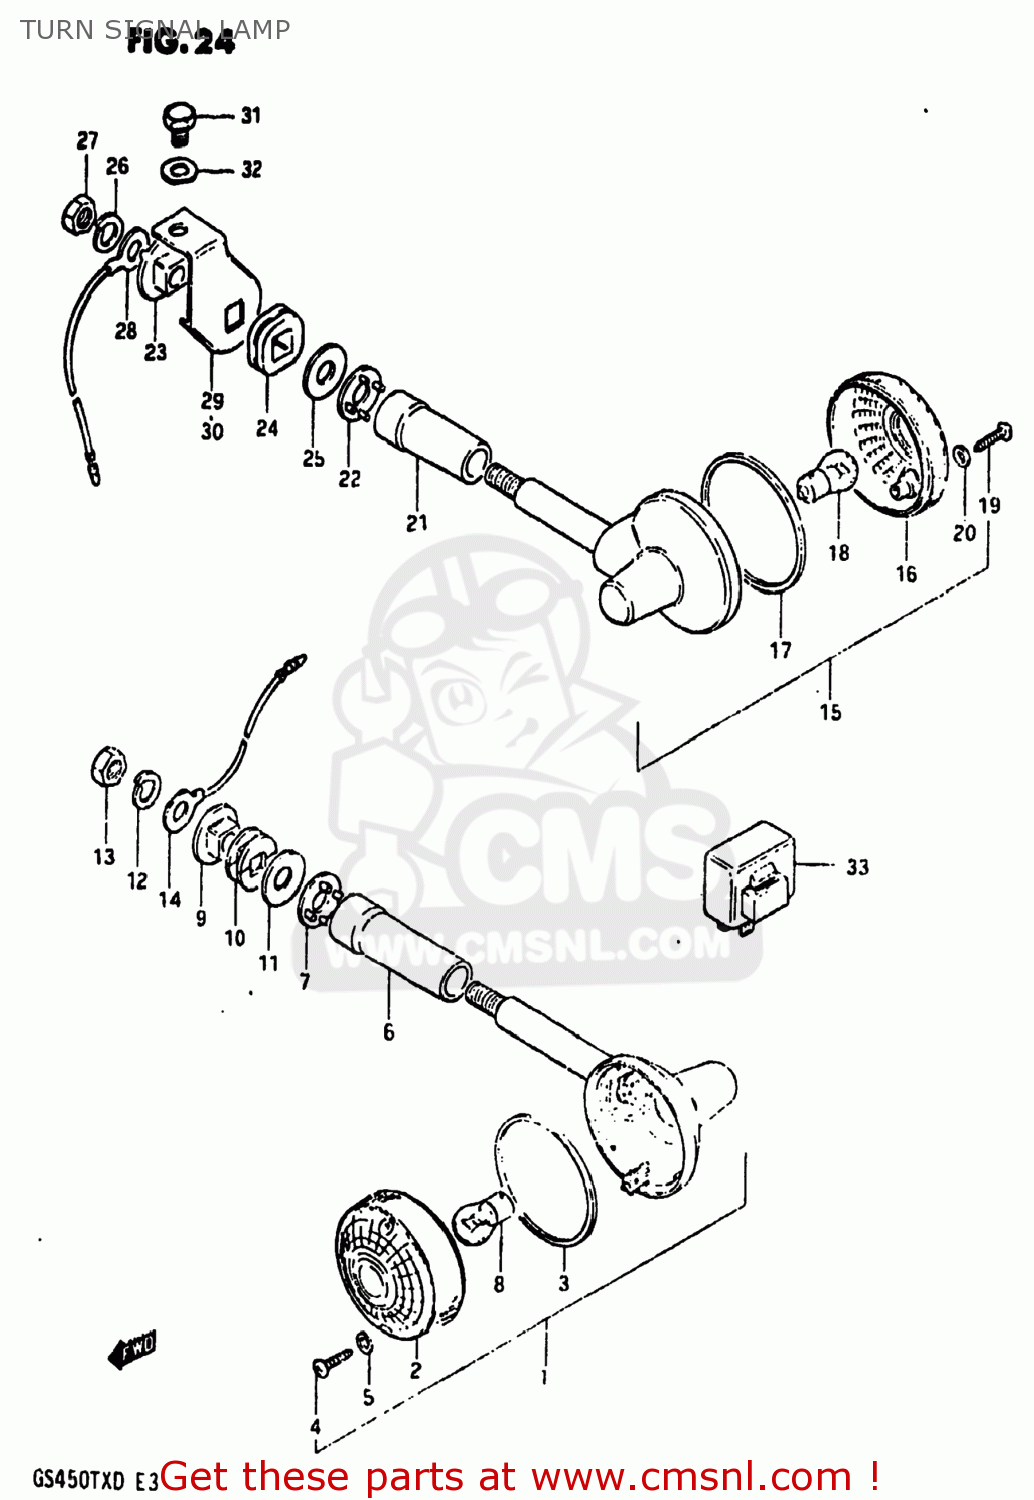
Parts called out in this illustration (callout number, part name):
1	LAMP ASSY,TURNSIGNAL
2	LENS
3	GASKET (NAS)
4	SCREW
5	GASKET (NAS)
6	COVER,STAY
7	SPACER
8	BULB(12V23W,STANLEY,A4577A)
9	SPACER
10	CUSHION
11	WASHER (10.5X30X2.3)
12	LOCK WASHER
13	NUT
14	LEAD WIRE,EARTH
15	LAMP ASSY,RR TURNSIGNAL
16	LENS
17	GASKET (NAS)
18	BULB(12V23W,STANLEY,A4577A)
19	SCREW
20	GASKET (NAS)
21	COVER
22	SPACER
23	SPACER
24	CUSHION
25	WASHER (10.5X30X2.3)
26	LOCK WASHER
27	NUT
28	LEAD WIRE,EARTH
29	BRACKET,RR TURNSIGNAL LAMP,R
30	BRACKET,REAR TURN SIGNAL
31	BOLT 8X12
32	WASHER
33	RELAY,TURN SIGNAL
